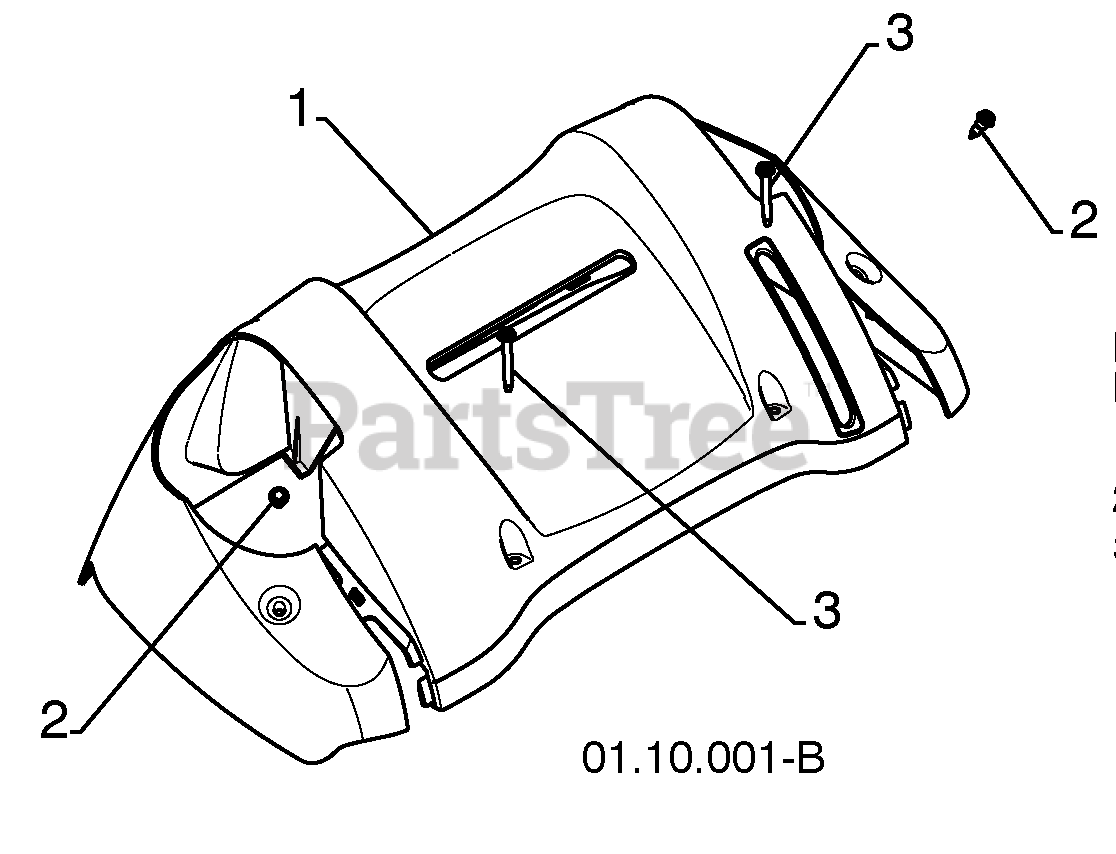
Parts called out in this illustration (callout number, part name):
1	CONSOLE PANEL
2	SCREW 10-24 X .625
3	SCREW 10-24 X 1.25
